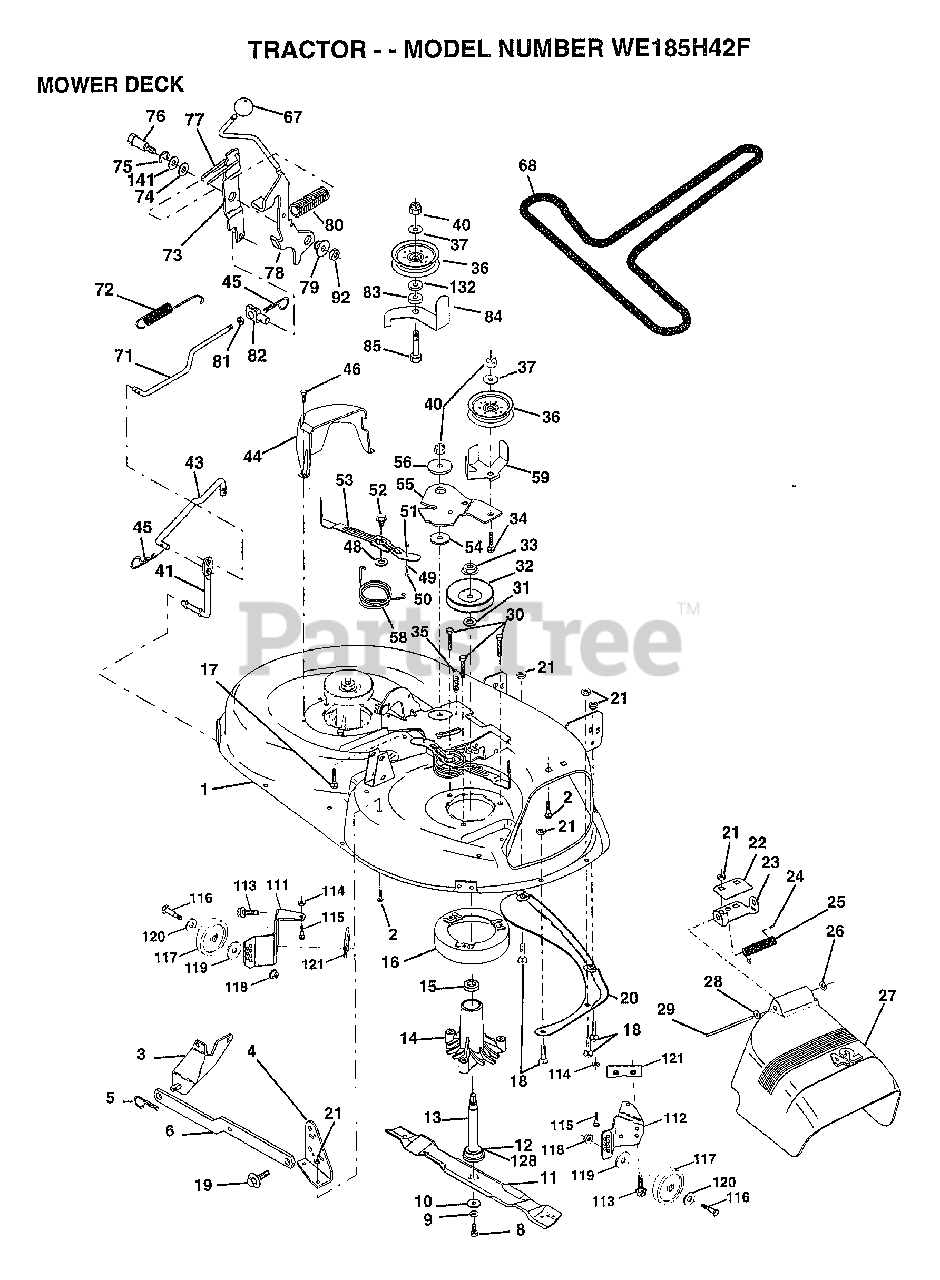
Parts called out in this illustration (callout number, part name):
1	"HOUSING ASSY.42"""
2	BOLT
3	BRKT ASM SWAY BAR
4	BRKT DECK SW BAR
8	BLADE BOLT
10	WASHER.HARD.BLADE
11	"BLADE.42"" HIPERF"
12	BEARING.BALL
14	HSG ASM MANDREL
15	BEARING
16	STRIPPER RND MWR
17	BOLT RDHD 3/8-16
18	BOLT
19	BOLT SHD 5/16-18
20	BAFFLE VORTEX 42
22	STIFFENER BRKT
23	DEFLECTOR BRKT
24	CAP-SLEEVE LT
25	SPRING TORSION
26	NUT PUSH M
27	DEFLECTOR.SHIELD
28	WASHER
29	HINGE ROD
30	"SCREW-THD ROLL,WA"
31	WASHER
32	PULLEY.MANDREL.42
34	BOLT
35	XMAS TREE FASTNER
36	FLAT IDLER PULLEY
37	WASHER
41	PIVOT ROD
43	ROD CLUTCH W/NIBS
44	GUARD MAND LH BLK
45	RETAINER M
46	SCREW.1/4-20X5/8
48	HARD SMALL WASHER
49	ROLLER ASM-CAM
50	SHOULDER BOLT
51	LOCKNUT
52	BOLT.SHLD.5/16-18
53	BRAKE PAD ARM ASM
54	HARDENED WASHER
55	ARM-IDLER
56	SPACER RETAINER
58	SPRING TORSN BRAK
59	GUARD IDLER TUV
67	KNOB.RD.7/16-14
68	BELT.V.T-PATH
71	ROD CLUTCH 38/42
72	RETURN SPRING
73	CLUTCH ARM SECOND
74	WASHER
75	RING
76	SHOULDER BOLT
77	SPRING KEEPER
78	LEVER.ASM.CLUTCH
79	BUSHING
80	SPRING.CLUTCH.MWR
81	NUT
82	TRUNION ADJ
83	WASHER
84	"KEEPER-BELT,FIXED"
85	BOLT
92	NUT
111	BRACKET.GWHL.LH.
112	BRACKET.GWHL.RH.
113	SCREW
116	BOLT M
117	WHEEL.GAGE.BLK.PL
118	LOCKNUT
119	WASHER
120	WASHER
121	BRACKET.EXTRD.GWL
128	WASHER.FELT.
132	WASHER GT
141	WASHER .T
